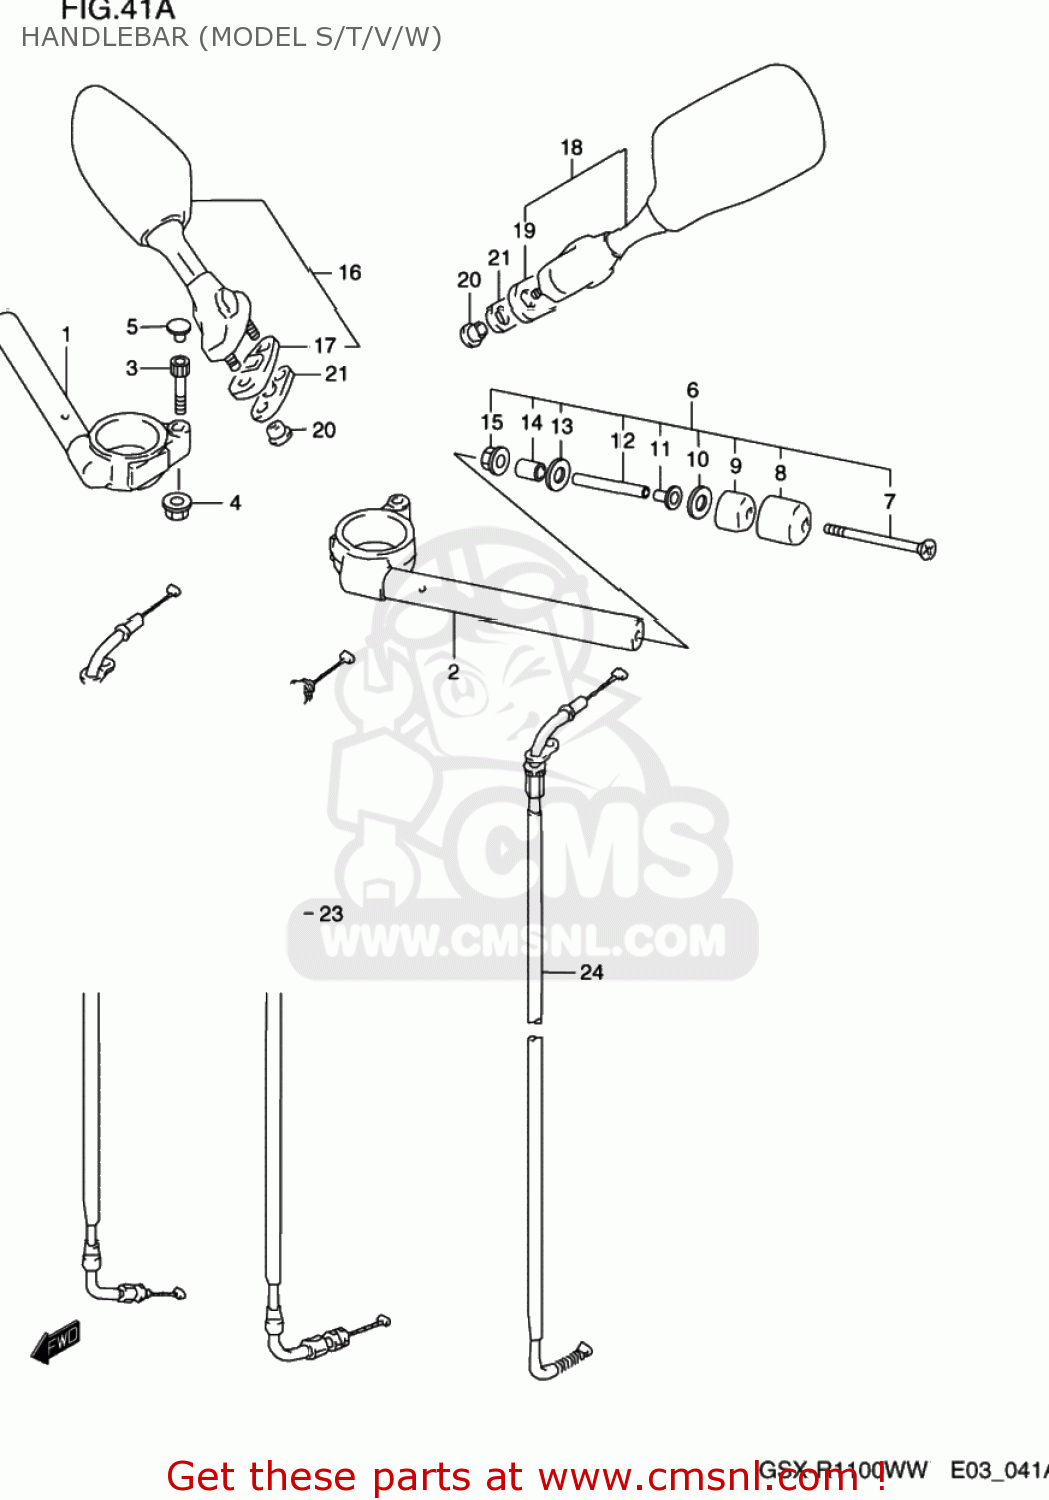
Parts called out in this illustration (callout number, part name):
1	HANDLEBAR,R
2	HANDLEBAR,L
3	BOLT
4	NUT
5	CAP(OD:12)
6	BALANCER SET
7	SCREW(6X125)
8	CAP,HANDLE BALANCER
9	BALANCER,HANDLEBAR
10	SPACER,BALANCER
11	EXPANDER,HANDLE BALANCER
12	SPACER,EXPANDER
13	WASHER
14	EXPANDER,HANDLE
15	NUT
16	MIRROR ASSY,RR VIEW,R
17	GASKET,RR VIEW MIRROR,R (NAS)
18	MIRROR ASSY,RR VIEW,L
19	GASKET,RR VIEW MIRROR,L (NAS)
20	NUT,RR VIEW MIRROR
21	CUSHION,RR VIEW MIRRORR
22	CABLE ASSY,THROTTLE NO.1
23	CABLE ASSY,THROTTLE NO.2
24	CABLE,STARTER
